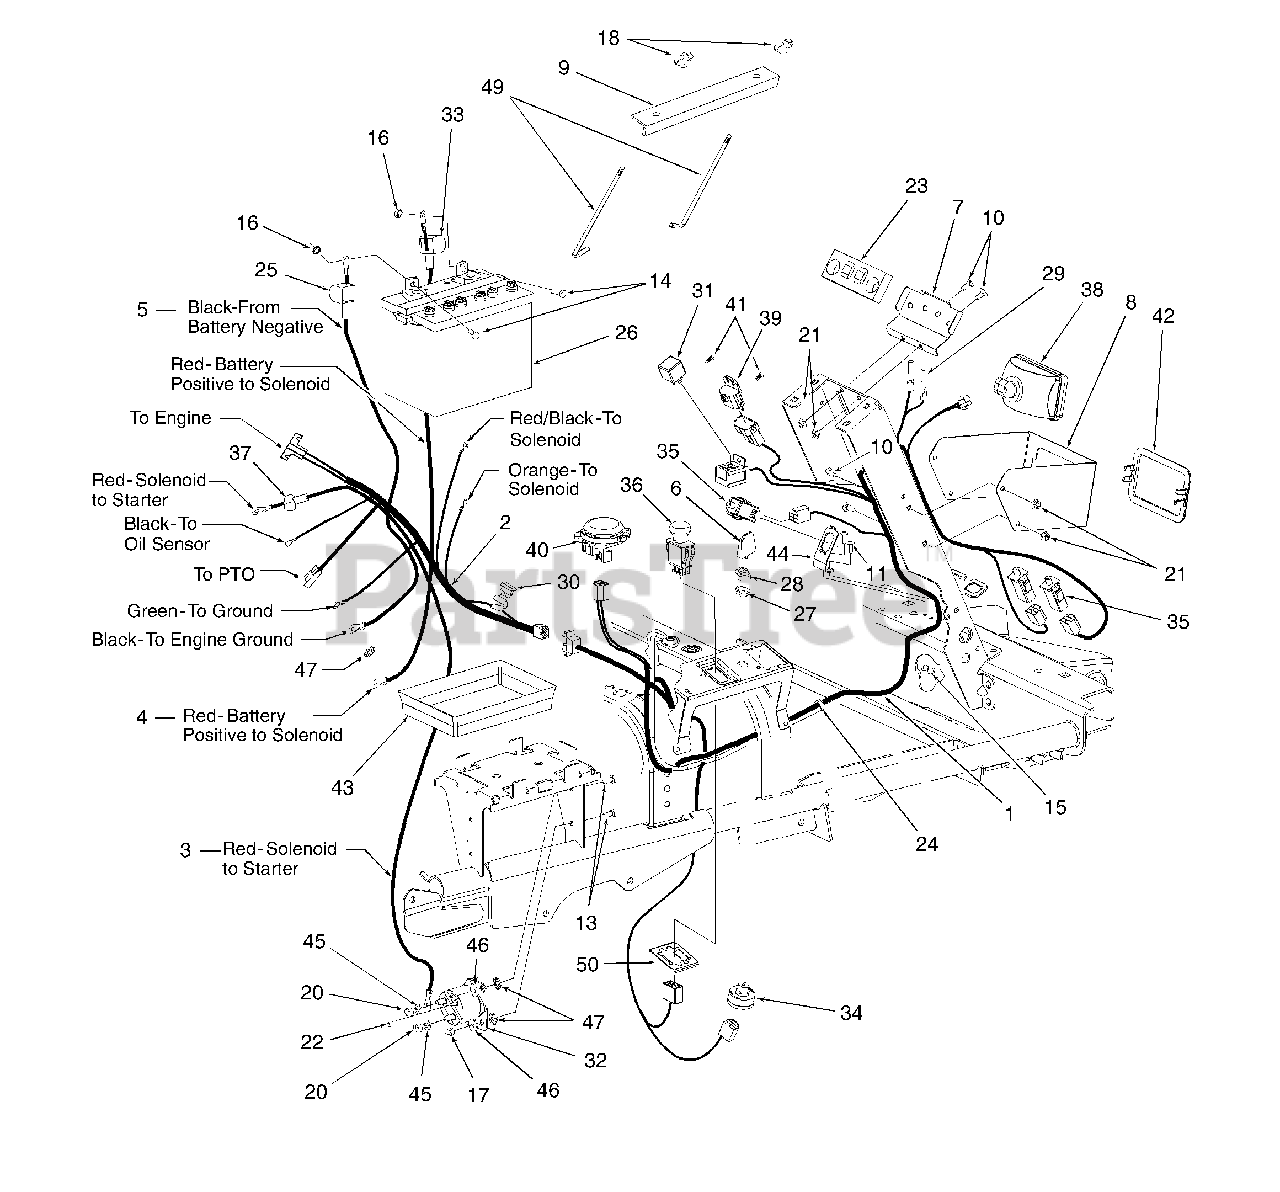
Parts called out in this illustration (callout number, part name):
1	Wire Harness, Main
2	Wire Harness, Engine
3	Cable, Battery, Red - 6 Ga. 24.75 in
4	Cable, Battery, Red - 6 Ga. 14.75 in
5	Cable, Battery, Black - 6 Ga. 8.75 in
6	Key, Ignition (Set of 2)
10	Bolt, Carriage, 1/4-20 x .62
11	Screw, Machine, #10-24 x 5/8
13	Screw, Hex Cap, 1/4-20 x .62 GR5
14	Screw, Hex Cap, 1/4-20 x .75 GR5
15	Nut, Hex Insert Lock, #10-24
16	Nut, Hex Sems, 1/4-20
17	Nut, Hex Center Lock, 1/4-20
18	Nut, Nylon Wing, 1/4-20
20	Nut, Hex, 5/16-18
21	Nut, Hex Flange Lock, 1/4-20
22	Nut, Hex Sems, #10-32
23	Foam Protector, Indicator Light
24	Cable Tie
25	Cover, Battery Terminal - Black
27	Nut, Ignition Switch, 5/8-32
28	Cap, Ignition Switch
29	Bulb, Indicator
30	Fuse, Mini, 20Amp
31	Relay
32	Solenoid Switch
33	Cover, Battery Terminal - Red
34	Switch, Ignition
35	Switch, Plunger Safety
36	Switch, PTO
37	Cover, Terminal - Red
38	Headlight Assembly
39	Sensor, Voltage
40	Switch, Seat
41	Retainer, Ratchet
42	Bezel, Headlight
43	Tray, Battery
44	Spring, Switch Mounting
45	Washer, Lock , 5/16
46	Washer, Bell, .265 x .75 x .062
47	Washer, Int./Ext. Lock, 1/4 ID
49	Rod, Battery Retainer
50	Bracket, PTO Switch Retainer
